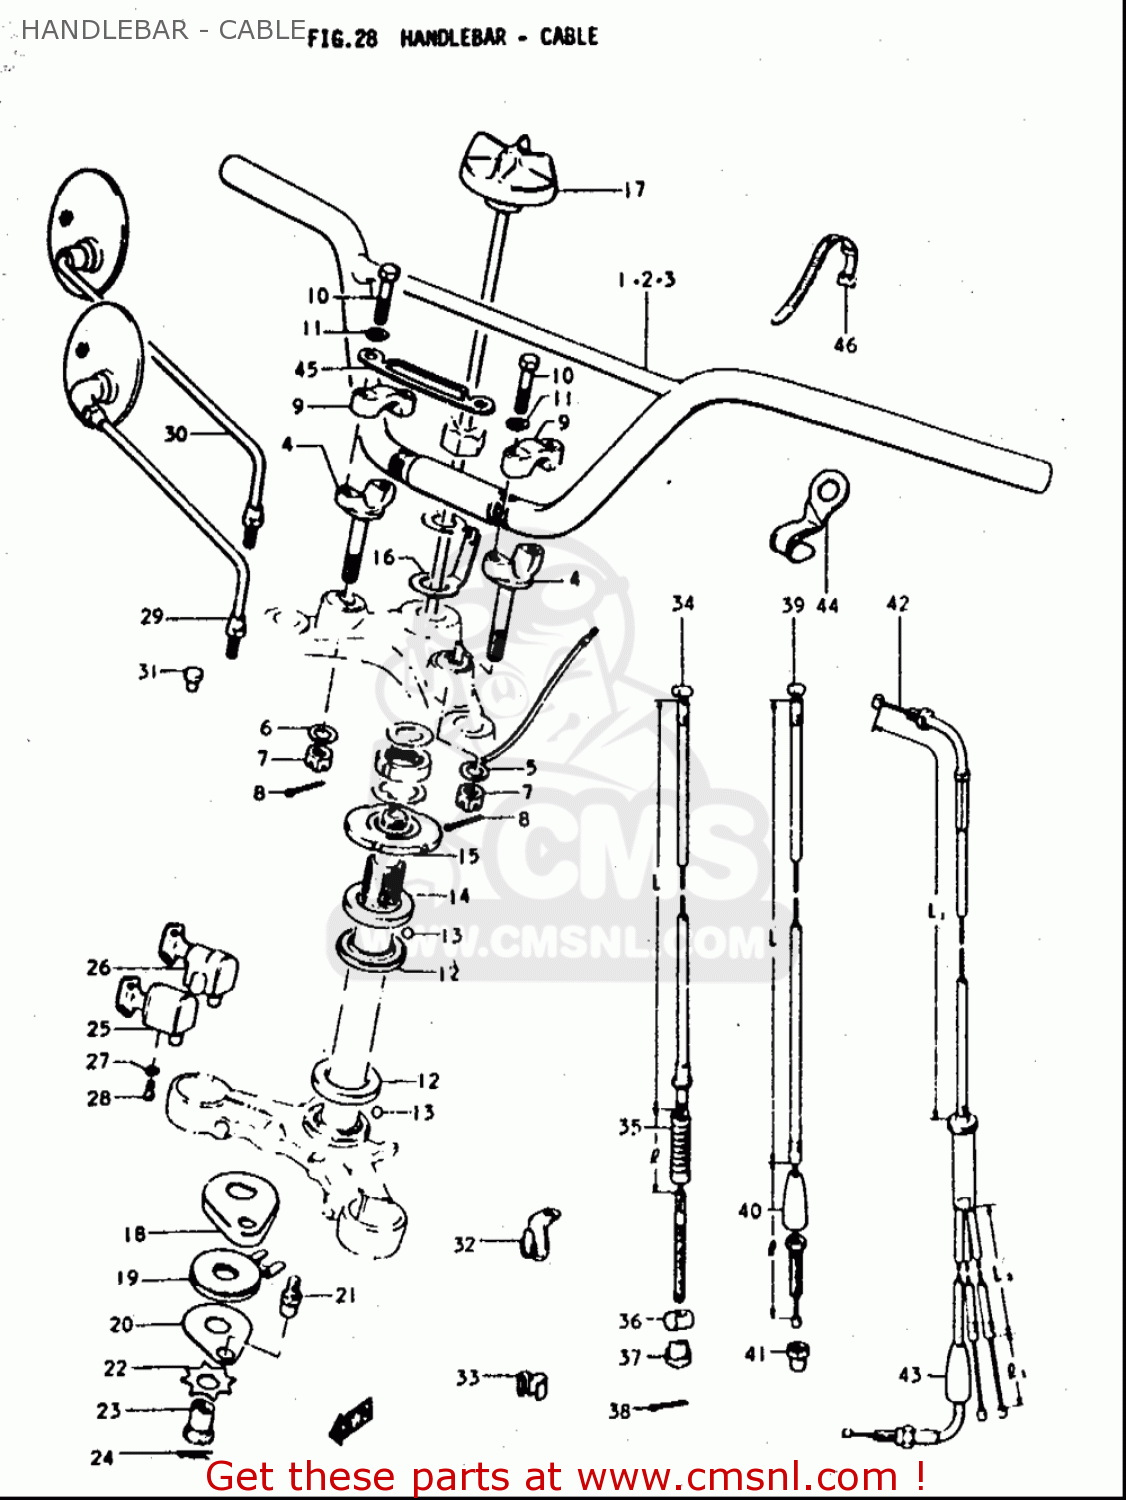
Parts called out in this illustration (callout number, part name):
1	HANDLEBAR
3	HANDLEBAR
6	WASHER(10.5X28X2.3)
7	NUT
9	HOLDER,HANDLEBAR
10	BOLT
11	WASHER,LOCK
12	LACE,STEERING INNER LWR
13	BALL
15	NUT,STEERING STEM
16	STOPPER, DAMPER KNOB
20	SPACER,STEERING DAMPER
21	BRACKET,STEERING DAMPER
22	SPRING, DAMPER ADJUST
23	HUB,HANDLEBAR DAMPER S
24	CLIP
27	WASHER,LOCK
28	SCREW
30	MIRROR ASSY,RE
31	CAP
33	CLIP
35	SEAL,DUST
36	PIN(13X18)
37	NUT
39	CABLE,CLUTCH
41	NUT
43	SEAL,DUST(7X18X30)
46	CLAMP(L:120)
